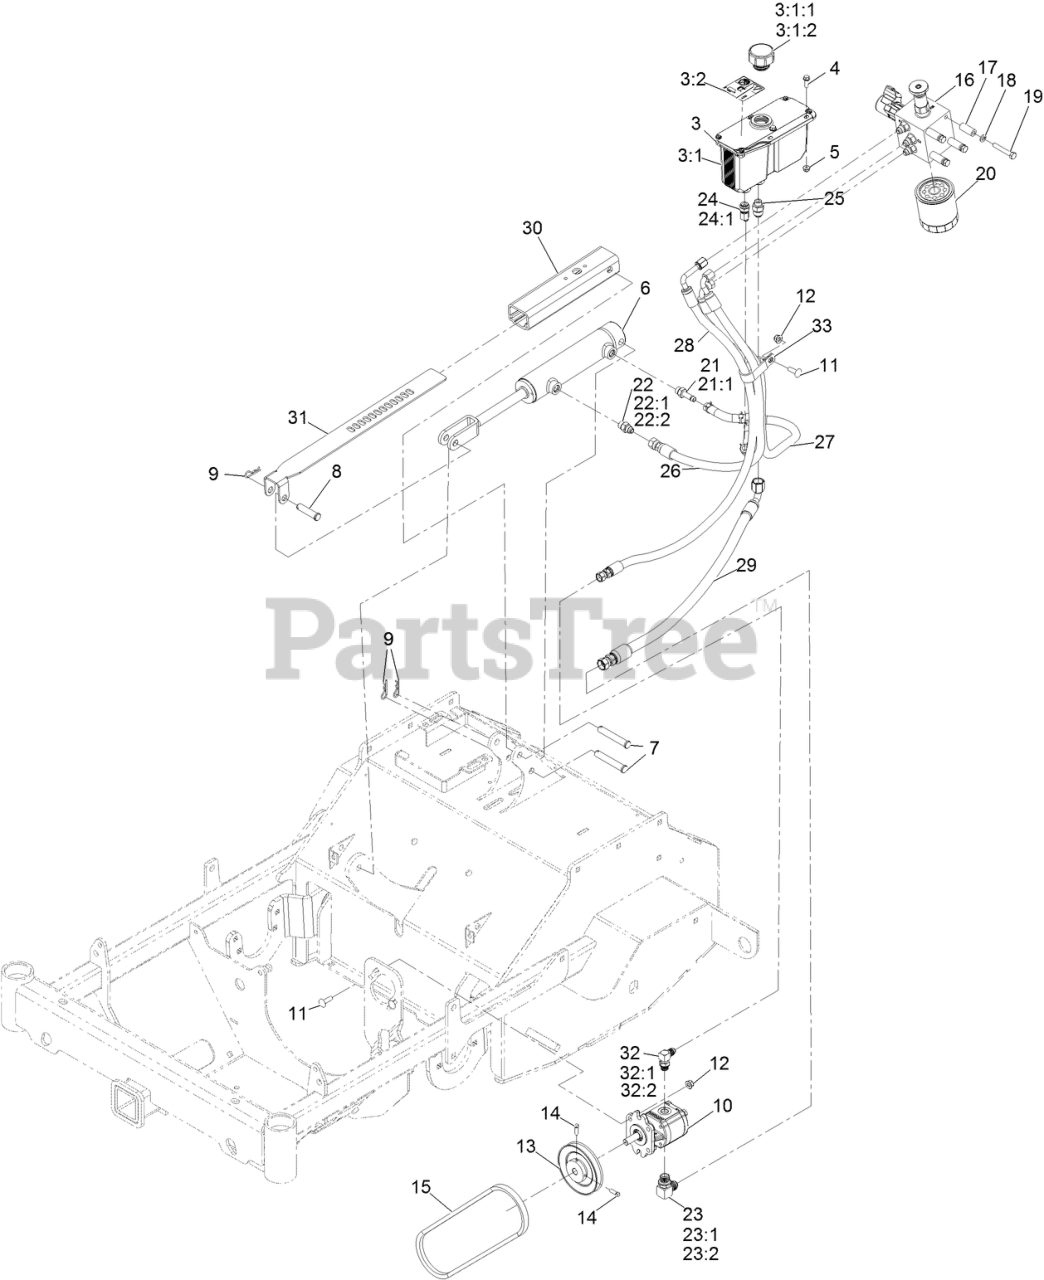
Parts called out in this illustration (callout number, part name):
3	RESERVOIR ASM
3:1	Reservoir-HYD
3:1:1	Cap-Reservoir, HYD
3:1:2	GASKET-CAP
3:2	DECAL-WARNING
4	SCREW-HWH
6	CYLINDER-HYDRAULIC
7	PIN-CLEVIS
8	PIN-CLEVIS
9	PIN-HAIR
10	PUMP-HYDRAULIC
11	SCREW-CARR
12	NUT-HF, NI
14	SCREW-SQH
16	MANIFOLD ASM
18	WASHER-LOCK
19	SCREW-HH
20	FILTER-25 MICRON, BI-DIRECTIONAL
21	ADAPTER-STRAIGHT
21:1	O-RING
22	FITTING-STRAIGHT
22:1	BOSS O-RING
23	FITTING-90 DEG
24	FITTING-BARBED, 45 DEG
24:1	O-RING
25	FITTING-STR
26	HYDRAULIC HOSE ASM
27	HYDRAULIC HOSE ASM
28	HYDRAULIC HOSE ASM
29	HYDRAULIC HOSE ASM
30	HOUSING-DEPTH CONTROL
31	BRACKET-DEPTH CONTROL
32	FITTING-90 DEG
32:1	BOSS O-RING
33	Clamp-R, Double
